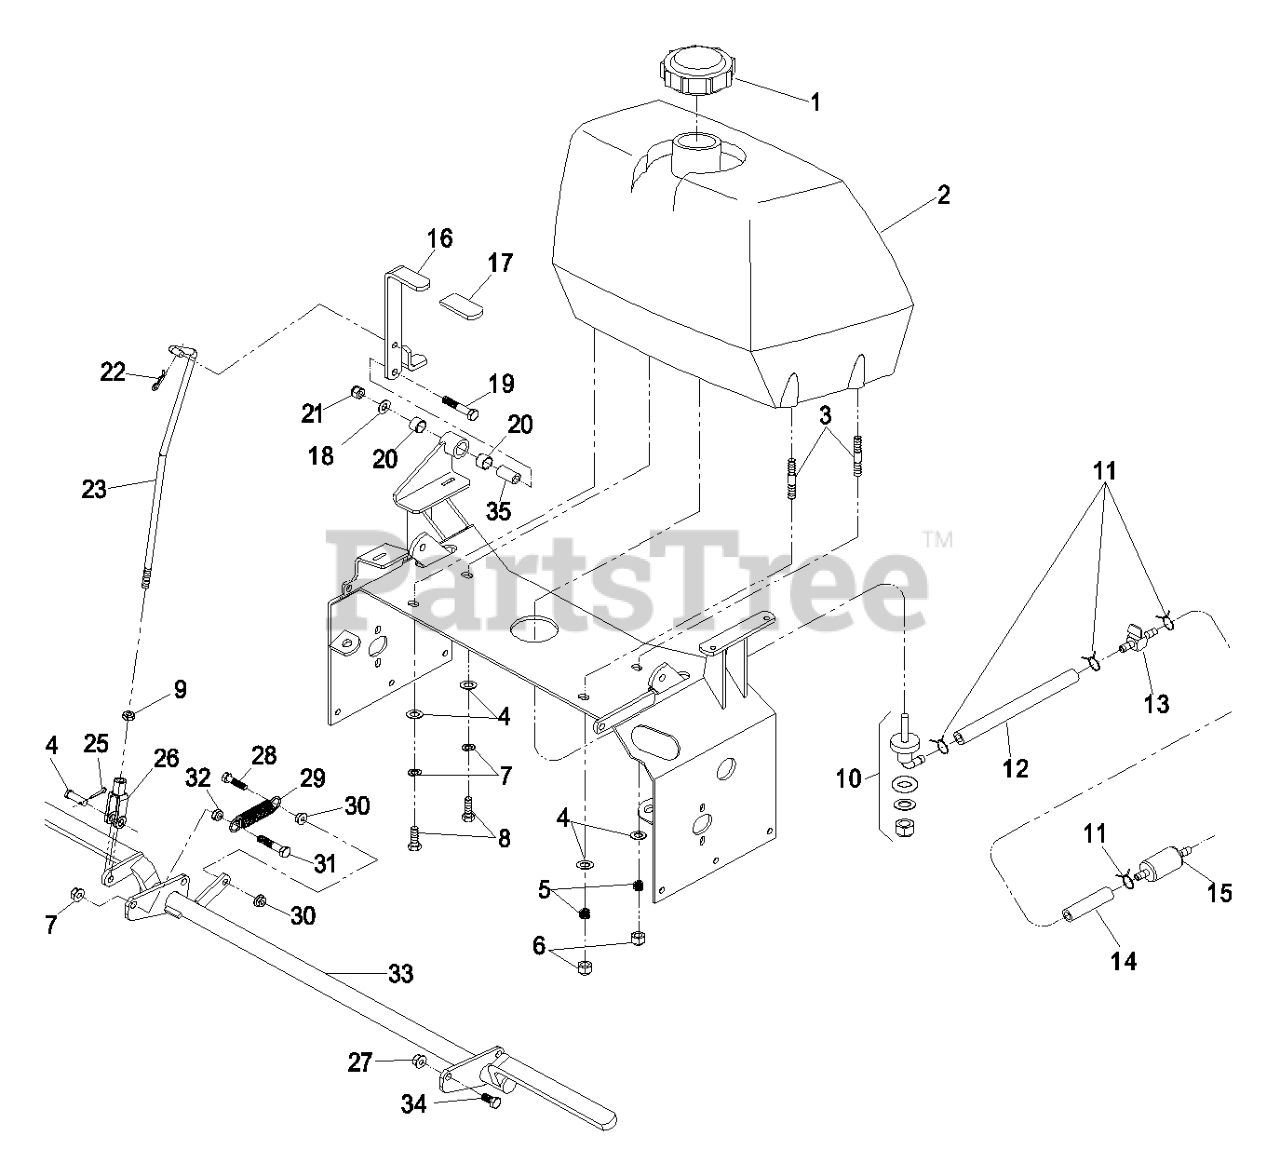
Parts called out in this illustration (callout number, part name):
2	ASM,FUEL TANK W/B
3	STUD
4	WASHER-PLAIN
5	SPRING-TANK, FUEL
6	NUT-LOCK, NI
7	WASHER-LOCK
8	SCREW-HH
9	NUT-HJ
10	FITTING-FUEL, BULKHEAD
13	VALVE-FUEL
14	HOSE-LINE, FUEL
15	Fuel Filter
17	GRIP-LEVER
18	WASHER-FLAT
19	SCREW-HH
20	SLEEVE-BUSHING
21	NUT-LOCK, NI
22	PIN-COTTER
23	LINKAGE,PARK BRAKE
24	PIN-CLEVIS
25	PIN-COTTER
26	YOKE-LINKAGE, BRAKE
27	NUT-HHF, WHIZ
28	SCREW-HH
29	SPRING-IDLER
31	SCREW-HH
32	NUT-JAM
34	SCREW-HH
35	BUSHING-PIVOT
